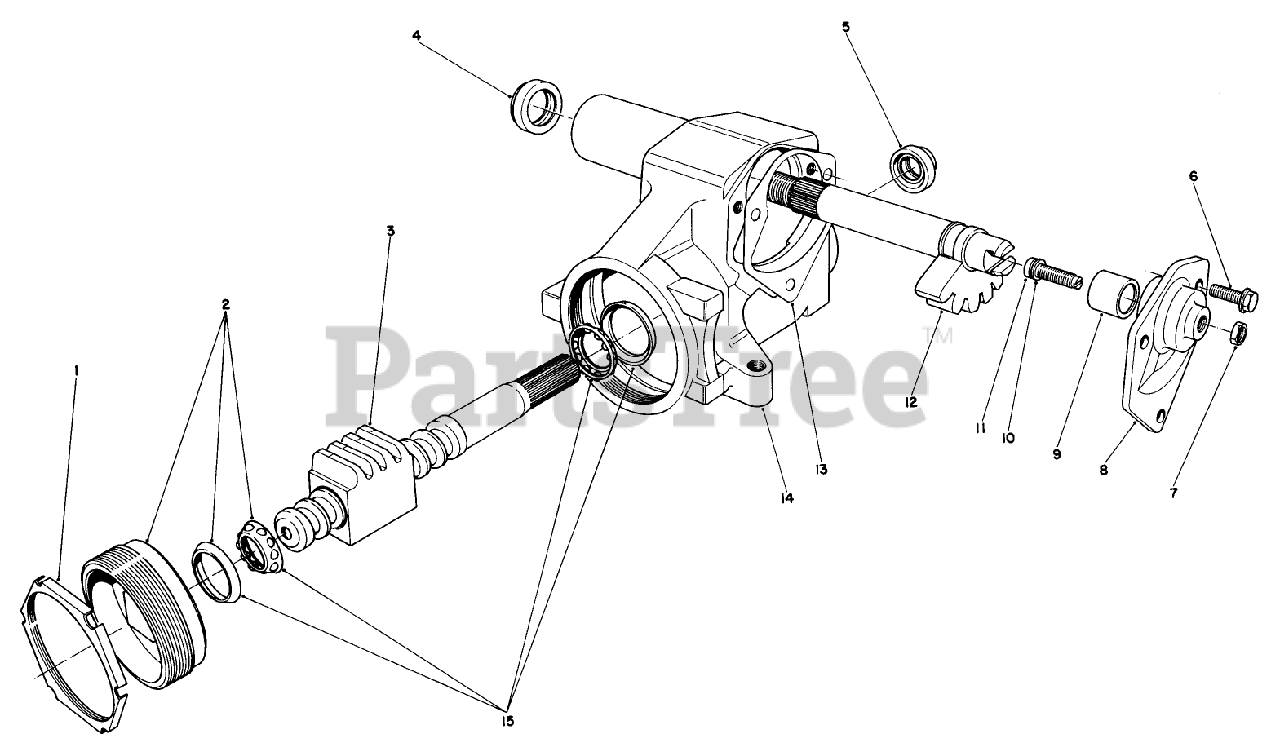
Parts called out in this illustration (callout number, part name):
1	Nut-Adjuster Lock
2	Adjuster Assembly
3	Steering Worm Assembly
4	Seal
5	Seal
6	Bolt-Flange Hex. Hd.
7	Nut
8	Side Cover Service Kit (Incl. Ref. #6, 9, 11 13)
10	Kit-Shim
11	Adjuster
12	Gear-Pitman Shaft
13	Gasket
14	Housing-Steering Gear
15	Assembly-Thrust Bearing
